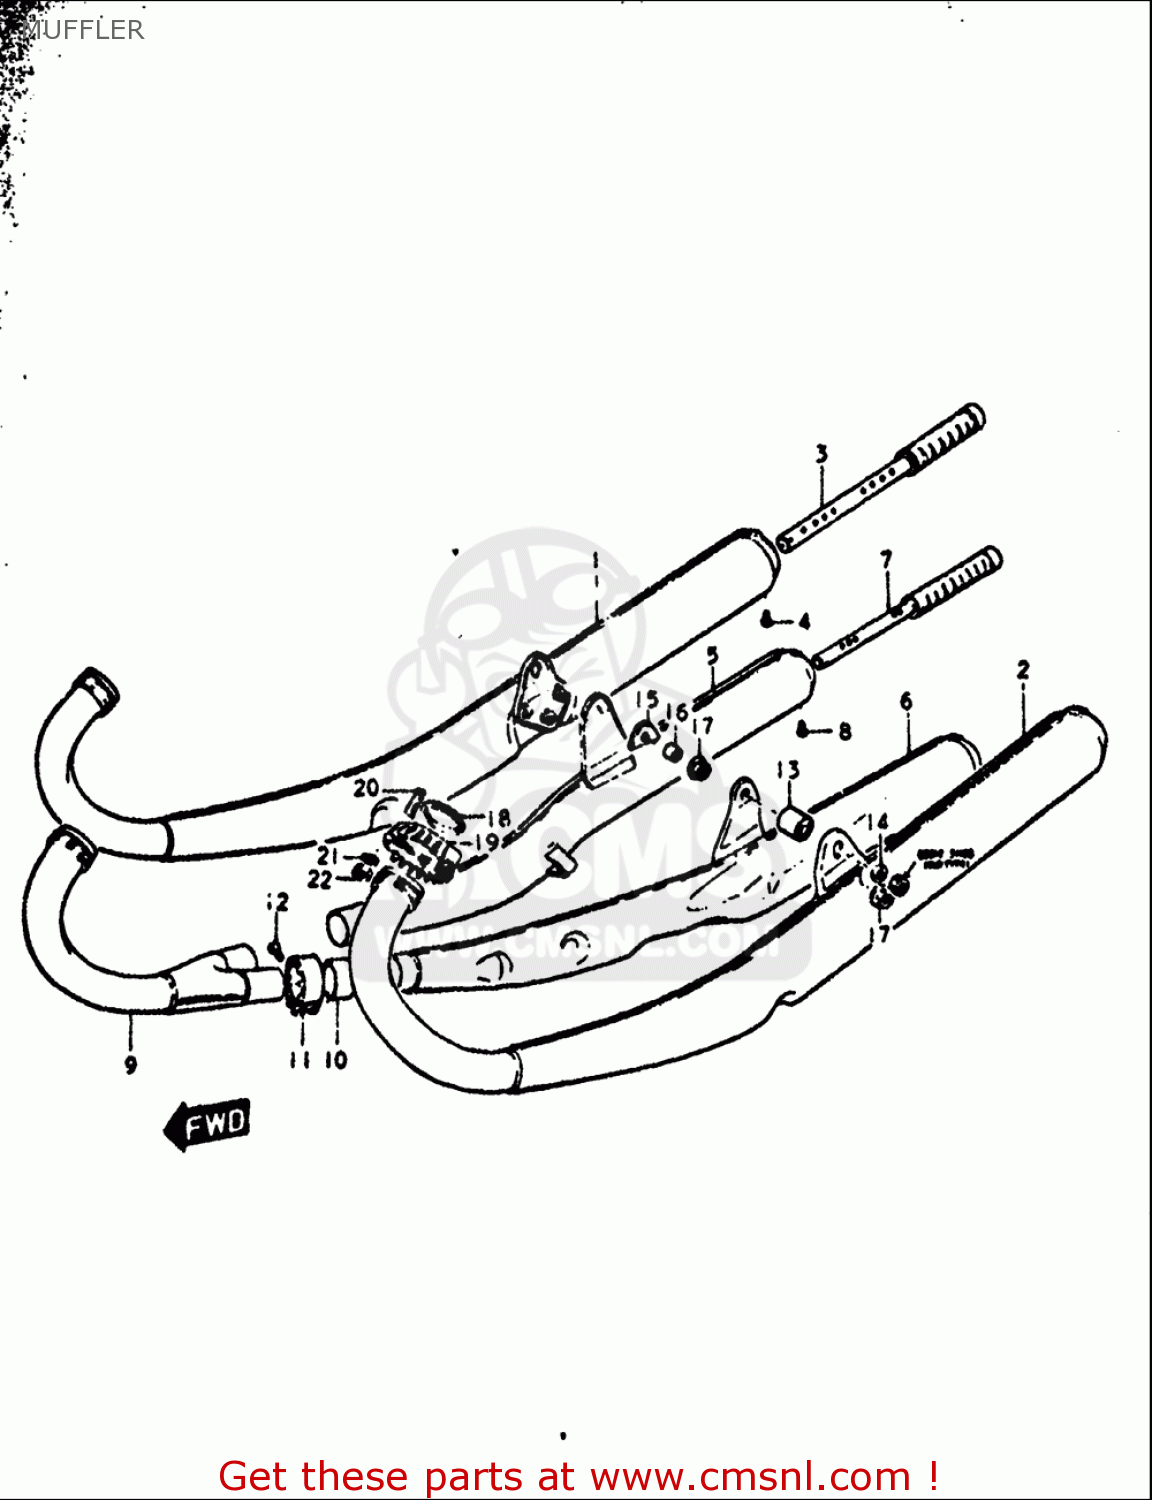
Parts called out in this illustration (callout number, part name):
4	SCREW(5X6)
7	PIPE,BAFFLE
8	SCREW(5X6)
10	CONNECTOR,MUFFLER
11	CLAMP
12	SCREW
13	BUSHING(10X23X35)
14	WASHER
15	DAMPER,MUFFLER SUPPORT BRACKET
16	SPACER(10.1X15X4.8)
17	NUT (M10X1.25X9)
18	GASKET,EXHAUST PIPE (NAS)
20	STUD
21	WASHER,LOCK
22	NUT
